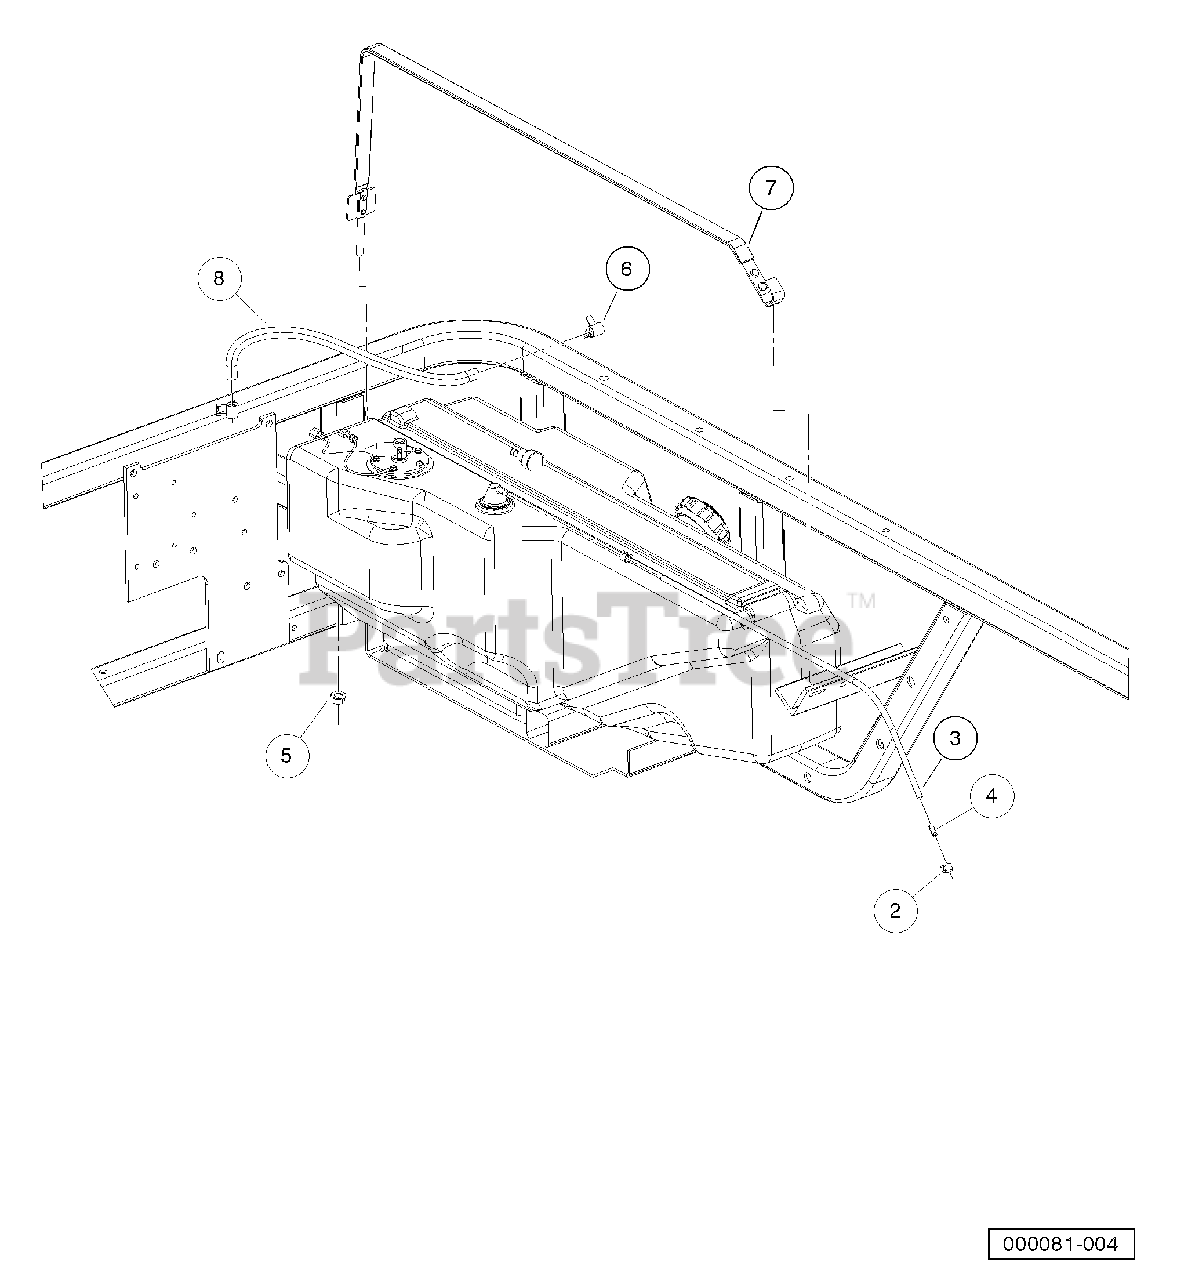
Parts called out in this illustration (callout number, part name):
1	Instl, Fuel System, Honda
2	Clamp, 0.301 ID Hose
3	Hose, Fuel, Vent, 22" Long
5	Nut,m8,all Metal Lock
6	Clamp, Hose, Ctb 13mm
7	Strap, Tank, Fuel
8	Hose, Tank To Filter, Fh680d
